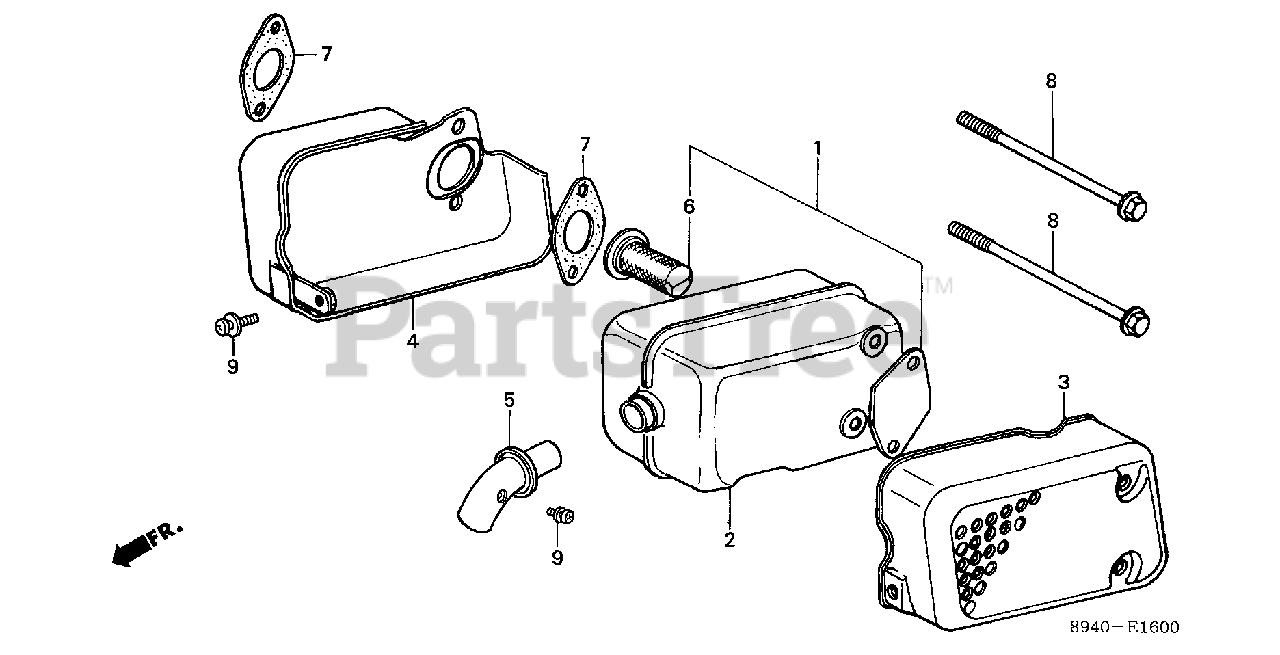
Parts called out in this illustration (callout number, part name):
1	ARRESTER KIT, SPARK
6	ARRESTER KIT, SPARK
7	GASKET, MUFFLER
8	BOLT, FLANGE (8X104)
